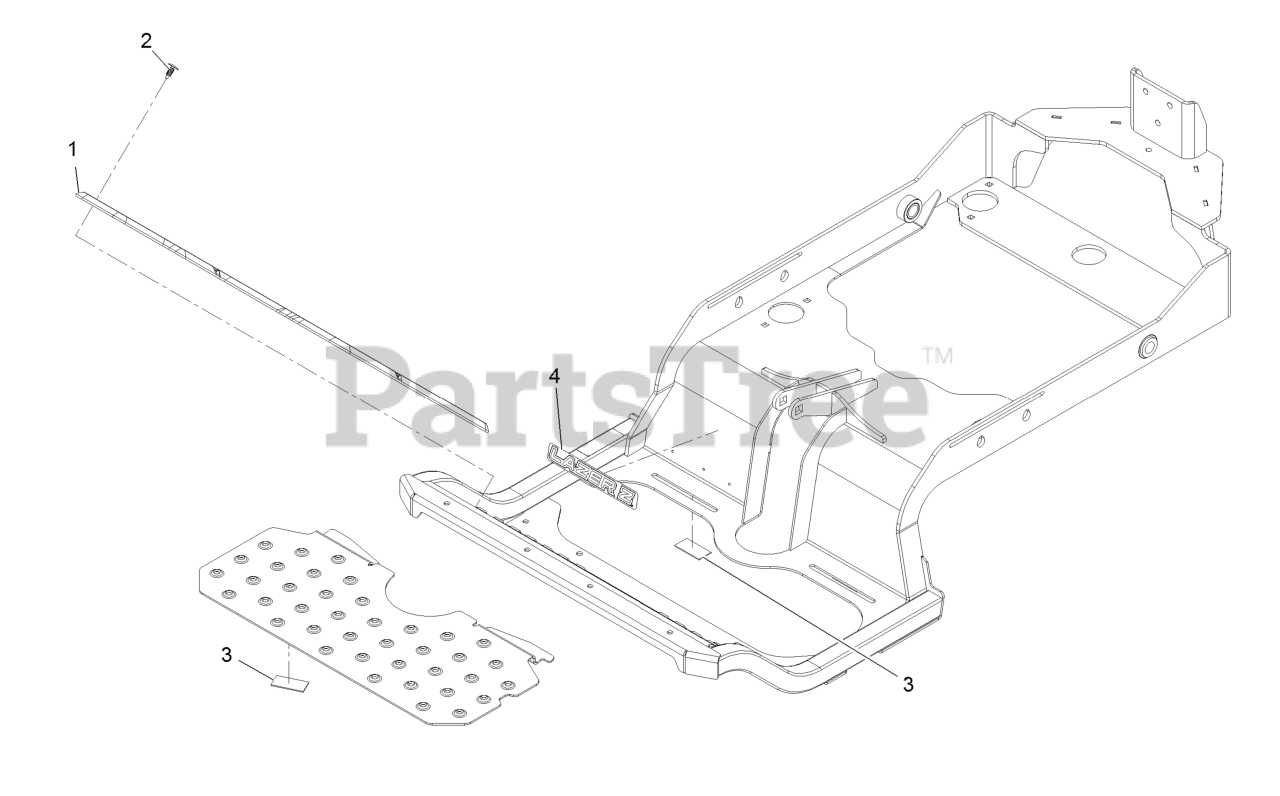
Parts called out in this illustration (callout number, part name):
1	FLOOR MAT
2	PLUG-PLASTIC
3	PAD-RUBBER
4	DECAL-LAZER LOGO
